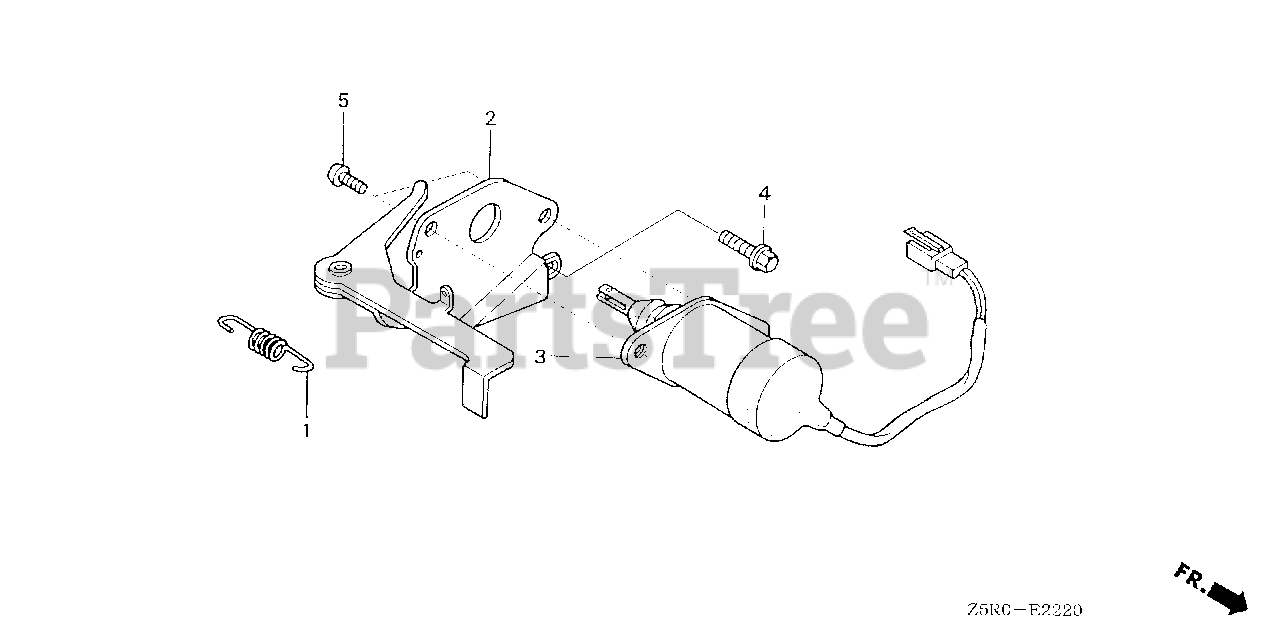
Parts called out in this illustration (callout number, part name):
1	SPRING, CHOKE RETURN
2	LEVER, THROTTLE
3	SOLENOID ASSY.
4	BOLT, FLANGE (6X12) (CT200)
5	SCREW, PAN (5X8)
